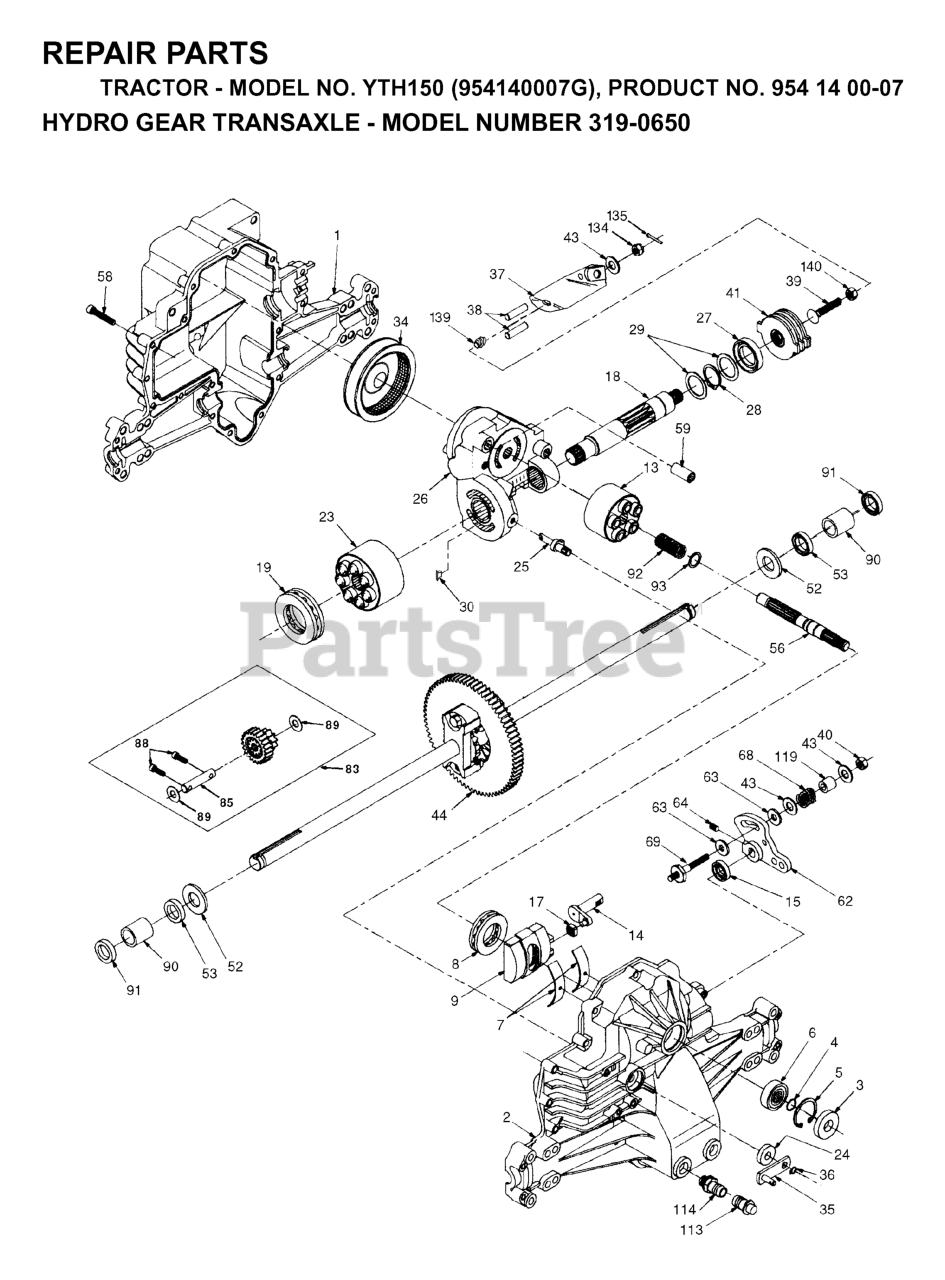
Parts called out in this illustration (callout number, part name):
3	Seal, Lip
8	Bearing, Thrust 30 x 52 x 13
13	Block, Cylinder Assembly
15	Seal, Lip
18	Shaft, Motor
19	Bearing, Thrust 42 x 68 x 16
23	Block, Cylinder Assembly
24	Seal, Lip 10 x 25 x 7
25	Actuator, Bypass
26	Center Section Assembly Kit
27	Seal, Lip 26 x 42 x 8
28	Ring, Retaining
29	Washer 26 x 35 x 1
34	Oil Filter Element
35	Arm, Bypass
36	Ring, Retaining
37	Arm, Actuating
38	Pin, Actuating
39	Bolt 5/16-24 x 1-3/4
40	Nut, Nylon Insert Hex Lock 5/16-24
41	Brake Rotor/Stator Kit
43	Washer 7/8 O.D. x 7/16 x .060
44	Differential Assembly
52	Washer 3/4 x 1.5 x .13
53	Seal .75 x 1.25 x .250
56	Shaft, Input
58	Bolt 1/4-20 x 1.38
59	Pin .5 OD x .43 ID x .750
62	Arm, Control
63	Puck, Dampener
64	Set Screw
68	Spring
69	Stud 5/16-24
83	Jack Shaft Assembly
91	Seal, Wiper
92	Spring, helical compression
93	Washer, Block Thrust
113	Cap, Vent Assembly
114	Fitting, O-Ring Assembly
119	Spacer
134	Nut, Castle 5/16-24
135	Pin, Cotter
139	Spring, Compression
140	Nut, Hex 5/16-24
